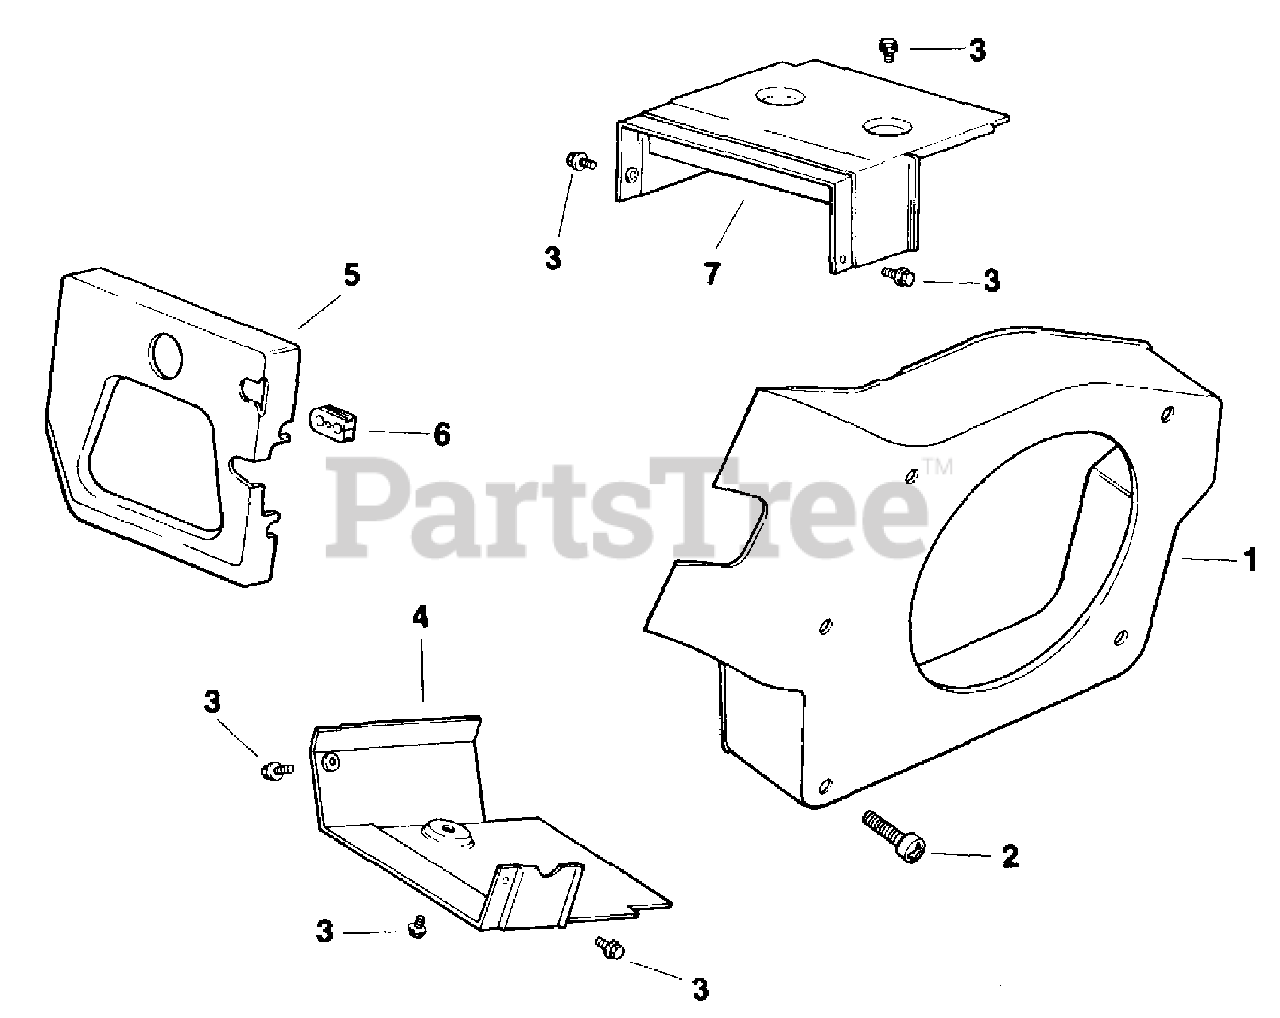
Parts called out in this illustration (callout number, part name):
1	HOUSING - USE 15 027 04
2	Screw, pan head M6x1.0x25.5
3	Screw, baffle mounting M5x0.8x10
4	BAFFLE - USE 15 063 07
5	BAFFLE - DISCONTINUED
7	BAFFLE - DISCONTINUED
